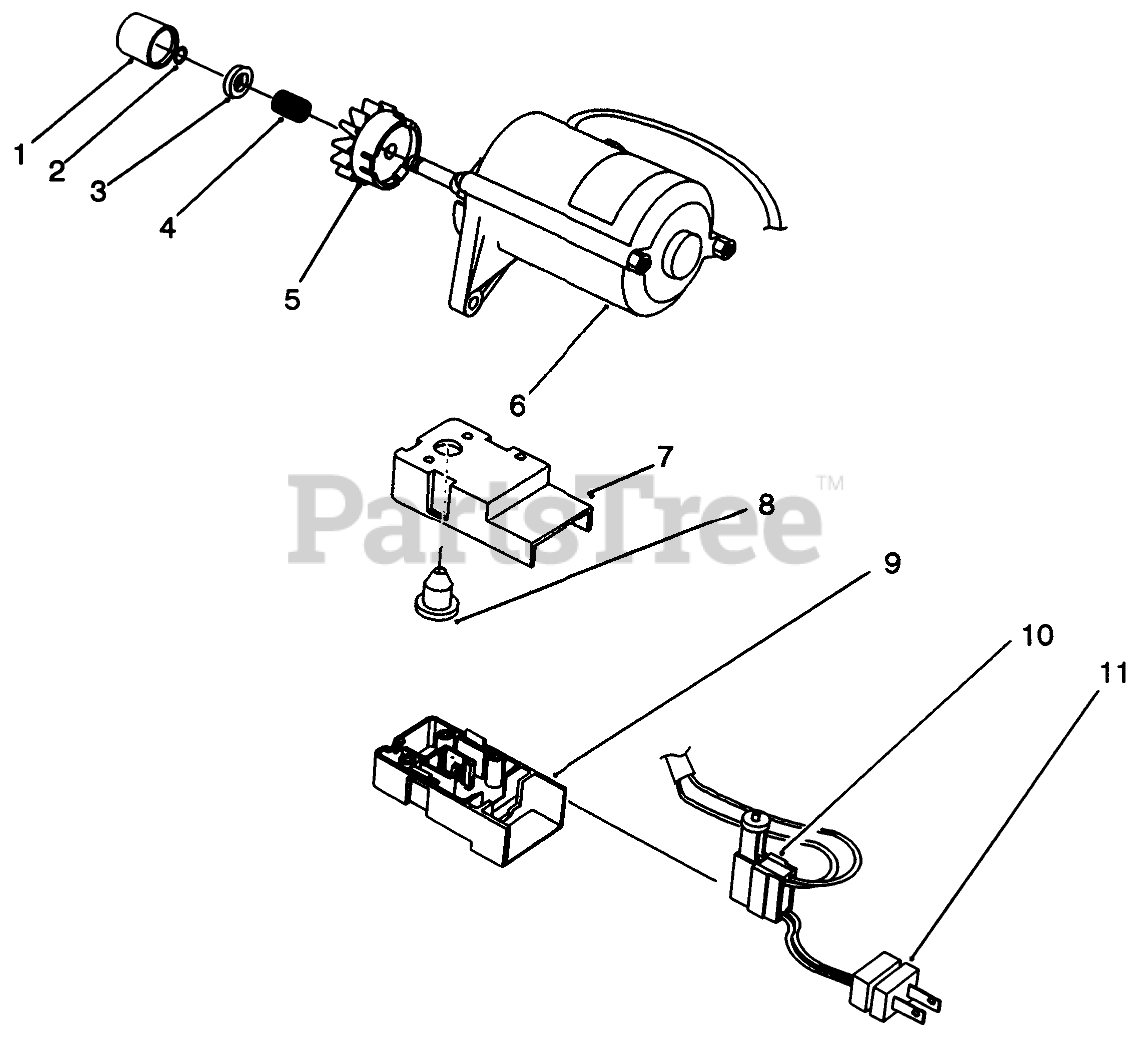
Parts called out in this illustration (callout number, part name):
1	CAP-PINION
2	RING-LOCK
3	PINION STOP
4	SPRING
5	PINION ASM
6	ASM-Switch Housing
7	Cap-Switch Housing
8	BOOT-SWITCH
9	OBS BASE X
10	SWITCH-STARTER
11	Plug
